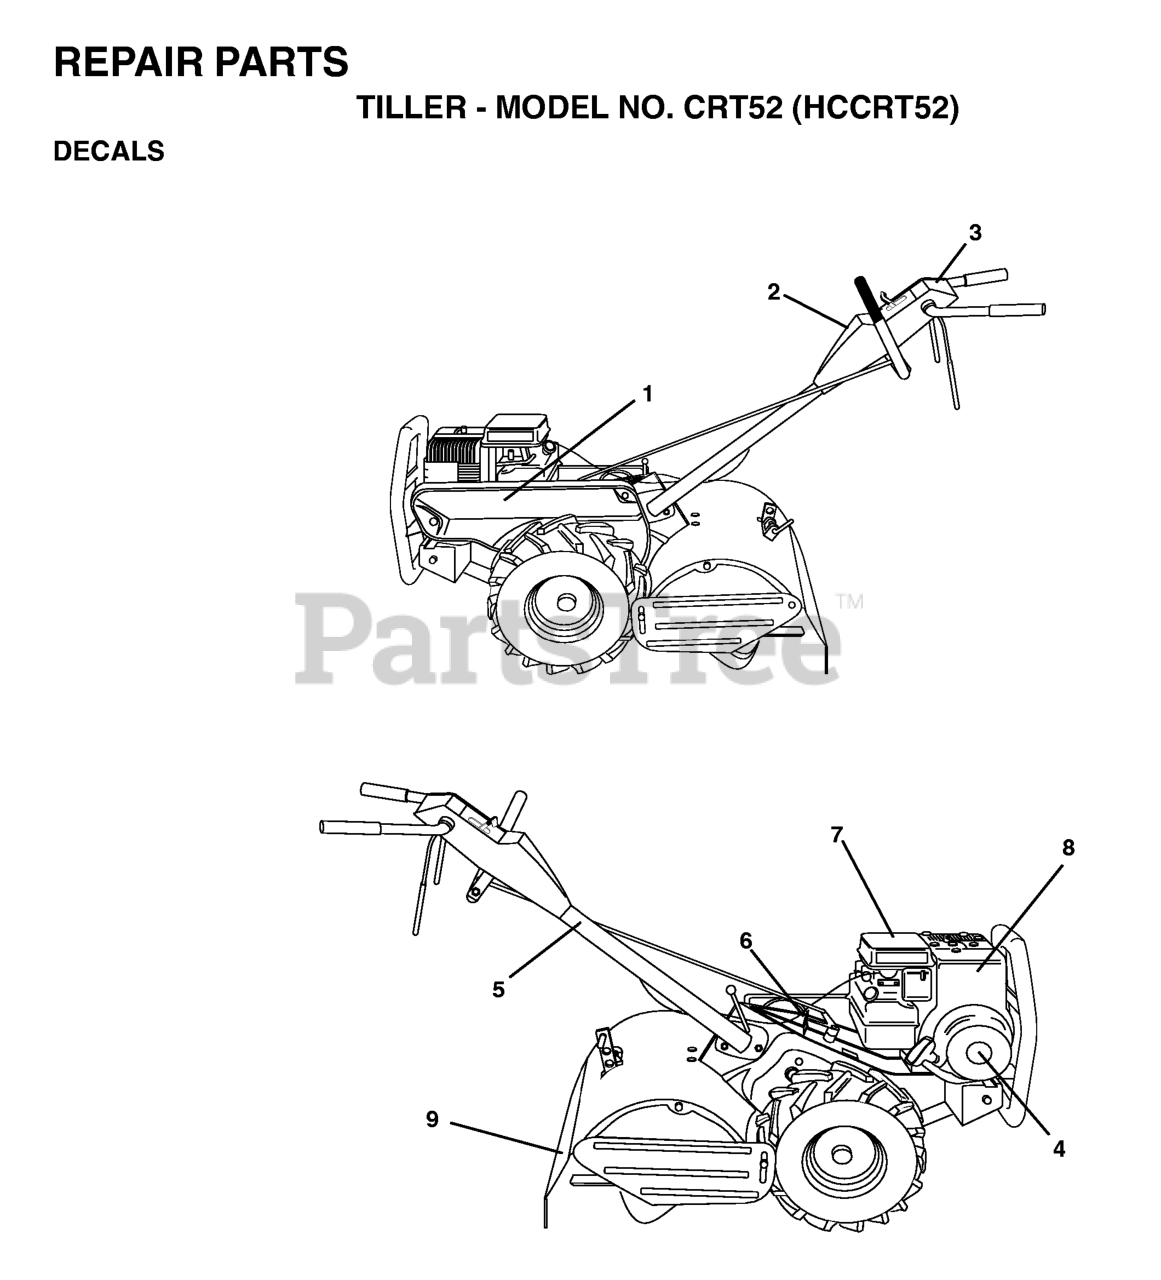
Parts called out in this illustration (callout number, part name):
1	DECAL, LOGO
2	DECAL, LOGO
3	DECAL, LOGO
4	Decal, 5.5 HP
5	DECAL TI (2 2)
8	DECAL, B & S ENGINE
9	DECAL TI
